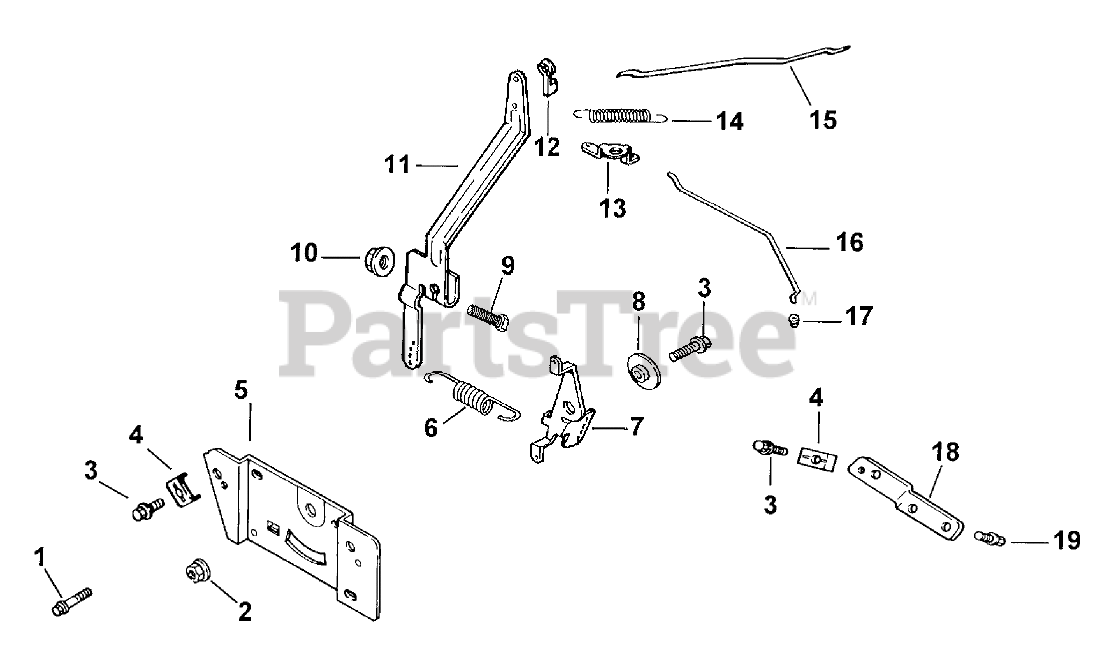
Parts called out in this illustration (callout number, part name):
1	Screw Socket
2	Nut, hex. flange M5x0.8
3	Screw-HF
4	Clamp
5	Plate, control
6	Spring, governor
7	Lever, throttle control
8	Spacer, throttle control
9	Screw
10	Nut
11	Lever, governor
12	Bushing-Linkage
13	Lever, choke-upper
14	Spring, linkage
15	Linkage, throttle
16	Linkage, choke-upper
17	Bushing-Linkage
18	Bracket, choke mount
19	Screw
